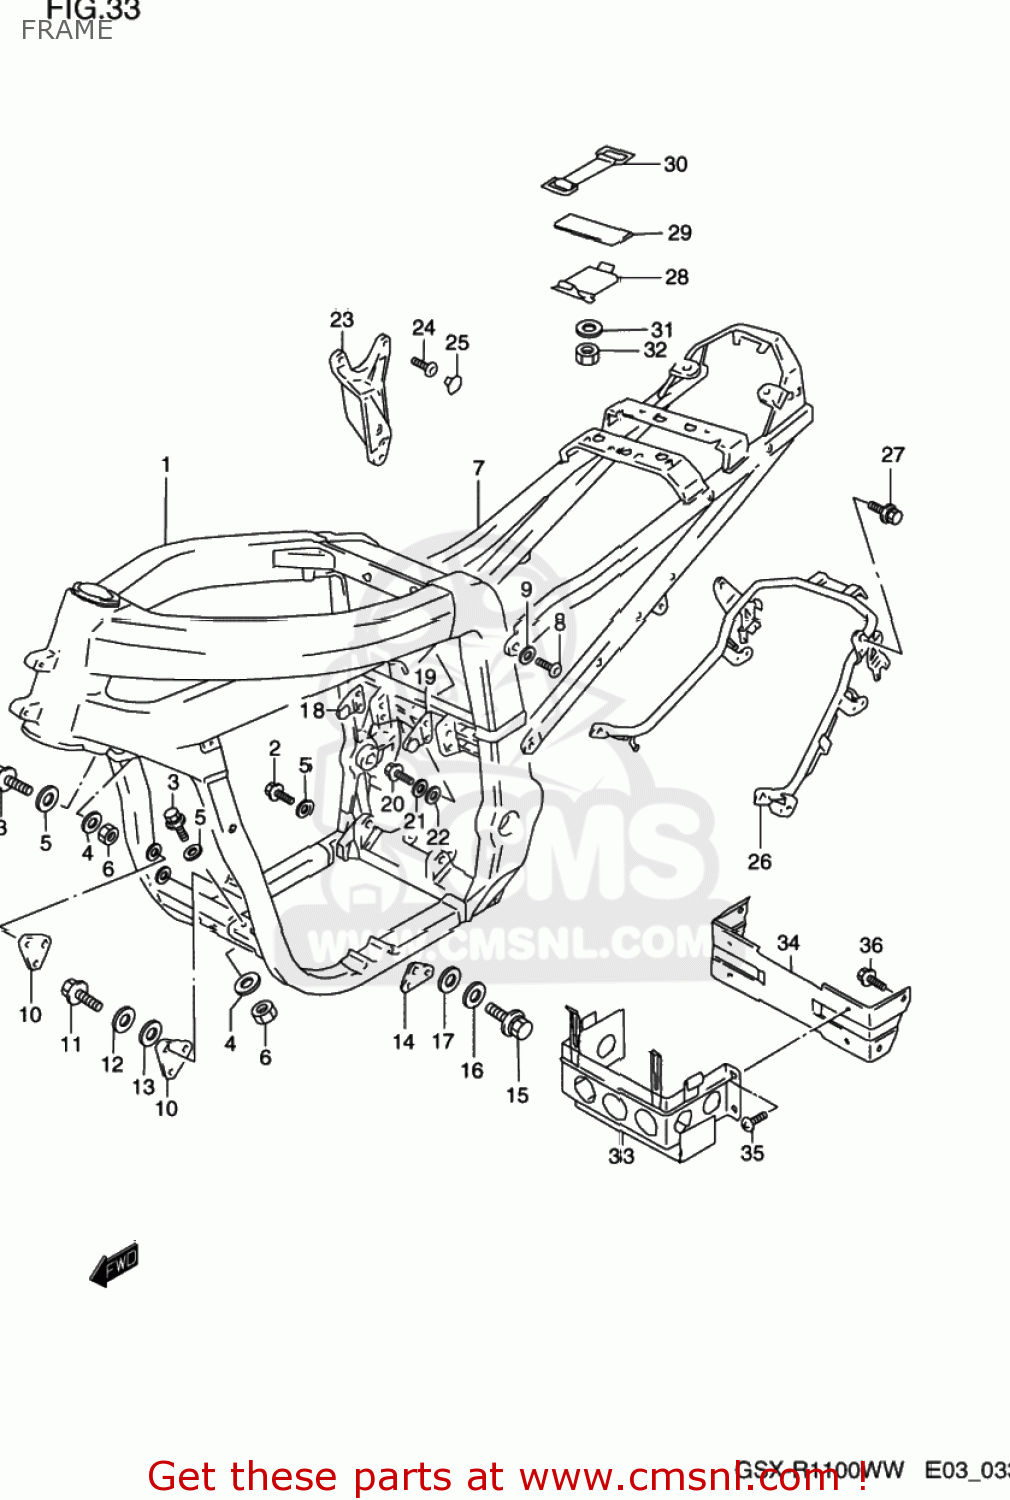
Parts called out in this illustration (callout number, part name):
1	FRAME SET
2	BOLT
3	BOLT
4	WASHER(10.5X20X2.3)
5	WASHER
6	NUT
7	RAIL,SEAT
8	BOLT,FOOTREST BRACKET
9	WASHER
10	PLATE,ENG MTG NO.1
11	BOLT
12	WASHER,LOCK
13	WASHER (8.2X20X1.6)
14	PLATE,ENG MTG NO.2,R
15	BOLT
16	WASHER,LOCK
17	WASHER (8.2X20X1.6)
18	PLATE,ENGINE MOUNTING NO.3
19	PLATE,ENG MTG NO.3,L
20	BOLT(8X22)
21	WASHER,LOCK
22	WASHER (8.2X20X1.6)
23	PLATE,ENG MTG UPR,L
24	BOLT(8X25)
25	CAP(OD:10)
26	GRIP,RR
27	BOLT
28	HOLDER,TOOL
29	COVER,HARNESS
30	BAND
31	WASHER
32	NUT
33	HOLDER,BATTERY
34	BRACKET,BATTERY HOLDER
35	SCREW 6X12
36	BOLT
